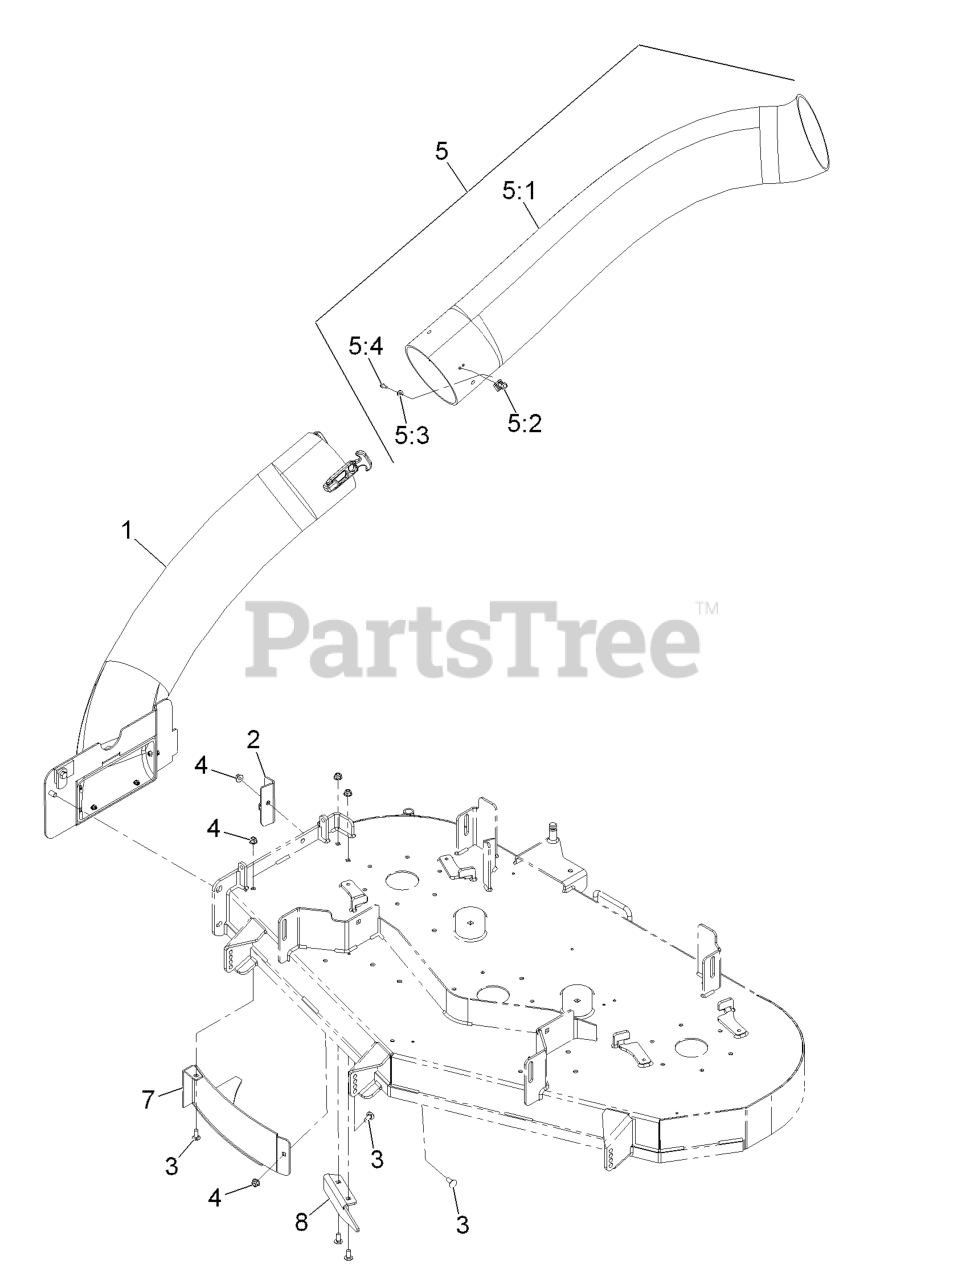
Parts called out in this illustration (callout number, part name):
1	TUBE AND FRAME ASM
2	BRACKET-BOOT MOUNT, 52 IN
2	BRACKET-BOOT MOUNT, 48 IN
3	SCREW-CARR
4	NUT-HF, NI
5	UPPER TUBE W/KEEPER ASM
5:1	TUBE-UPPER
5:2	LATCH-KEEPER
5:3	WASHER-FLAT
5:4	SCREW-PPH
7	WLD,DISCHARGE BAFFLE
8	BAFFLE-DISCHARGE
